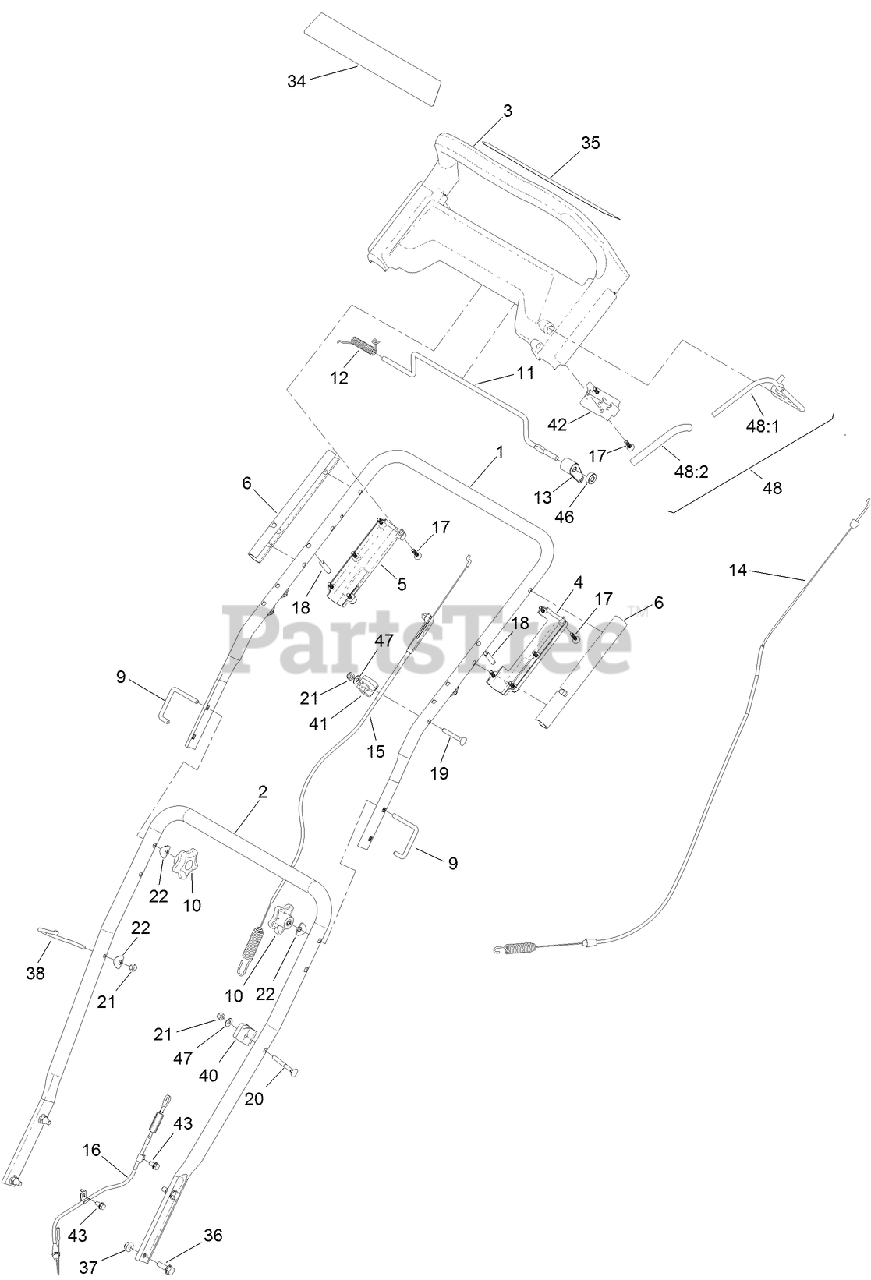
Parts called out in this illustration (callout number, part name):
1	HANDLE-UPPER
2	HANDLE-LOWER
3	HANDLE
4	HANDLE-BOTTOM, LH
5	HANDLE-BOTTOM, RH
6	SLEEVE HANDLE
9	LOCK-HANDLE
10	KNOB-HANDLE
11	BAR-CONTROL, TRACTION
12	SPRING-TORSION
13	LEVER-TRACTION
14	CABLE-TRANSMISSION
15	CABLE-ROTOR, UPPER
16	CABLE-ROTOR, LOWER
18	PIN-DOWEL
19	SCREW
20	SCREW-HANDLE
21	NUT-LOCK, NI
22	WASHER
34	DECAL-DISPLAY
35	DECAL-CONTROL, PANEL
36	SCREW-HHF
37	NUT-HF, NI
38	GUIDE-ROPE
40	ANCHOR-CABLE, UPPER
41	CABLE-GUIDE
42	BAIL-MOUNT
43	SCREW-HWH
46	SPACER
47	WASHER-FLAT
48	BAIL ASM
48:1	BAIL-AUGER
48:2	COVER-BAIL
